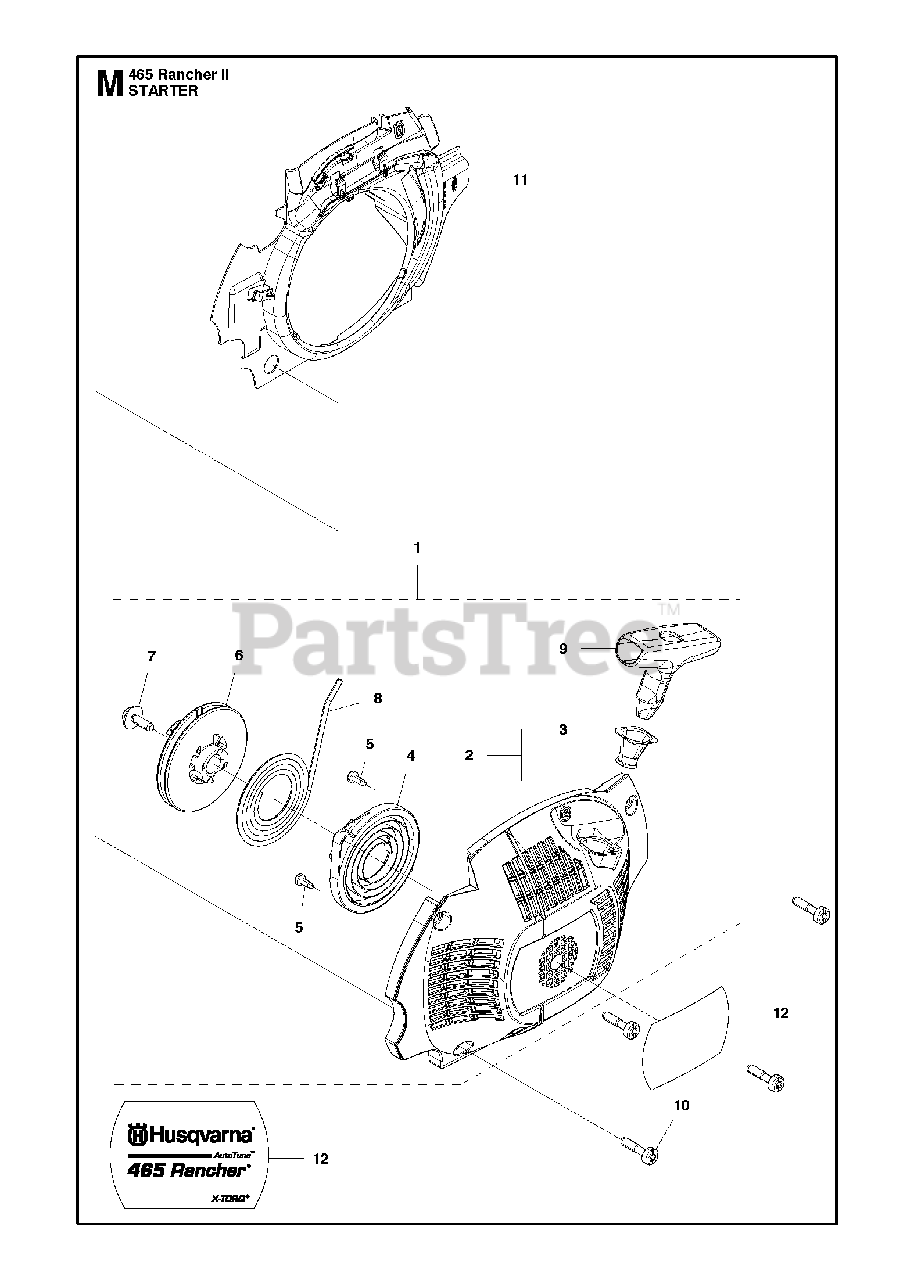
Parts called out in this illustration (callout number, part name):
1	STARTER ASSY
2	STARTER HOUSING
3	SLEEVE
4	RETURN SPRING
5	SCREW
6	STARTER PULLEY
7	SCREW
8	STARTER ROPE
9	HANDLE
11	AIR BAFFLE
